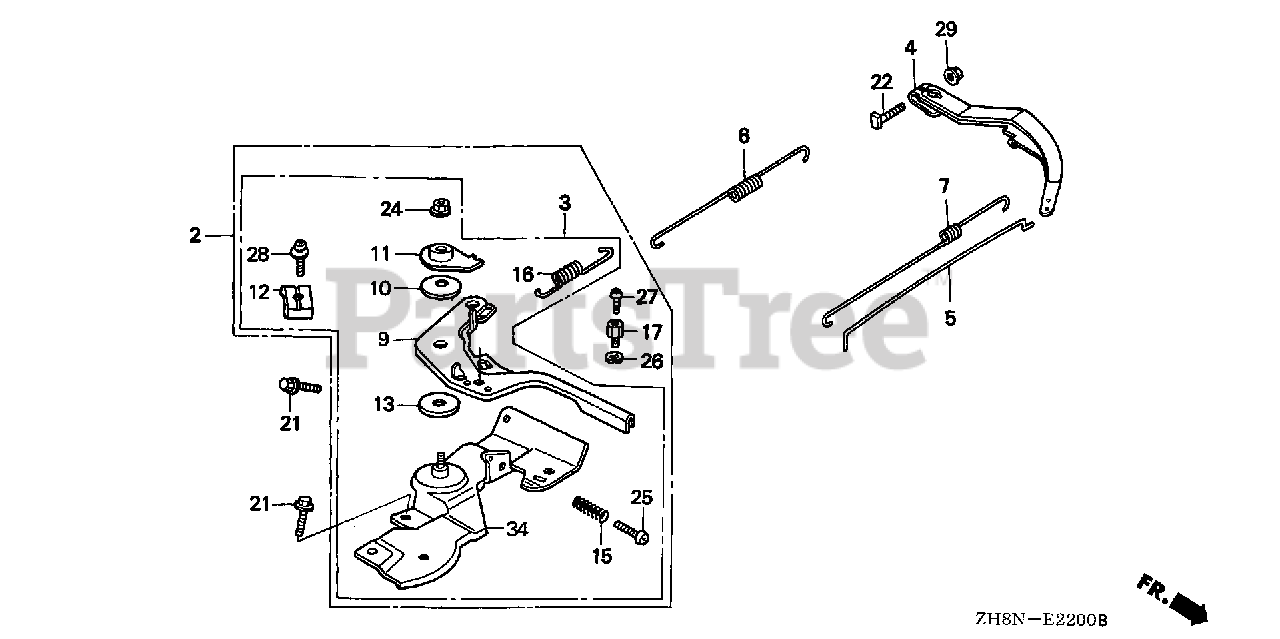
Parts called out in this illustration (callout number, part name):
2	CONTROL ASSY. (TB560)
4	ARM, GOVERNOR
5	ROD, GOVERNOR
6	SPRING, GOVERNOR
7	SPRING, THROTTLE RETURN
9	LEVER, CONTROL
10	SPRING, LEVER
11	WASHER, CONTROL LEVER
12	HOLDER, CABLE
13	SPACER, CONTROL LEVER
15	SPRING, CONTROL ADJUSTING
16	SPRING, CABLE RETURN
17	HOLDER, WIRE
21	BOLT, FLANGE (6X12) (CT200)
22	BOLT, GOVERNOR ARM
24	NUT, SELF-LOCK (6MM)
25	SCREW, PAN (5X25)
26	CIRCLIP (5MM)
27	SCREW, PAN (4X6)
28	SCREW, PAN (5X16)
29	NUT, FLANGE (6MM)
34	BASE, CONTROL (REMOTE)
